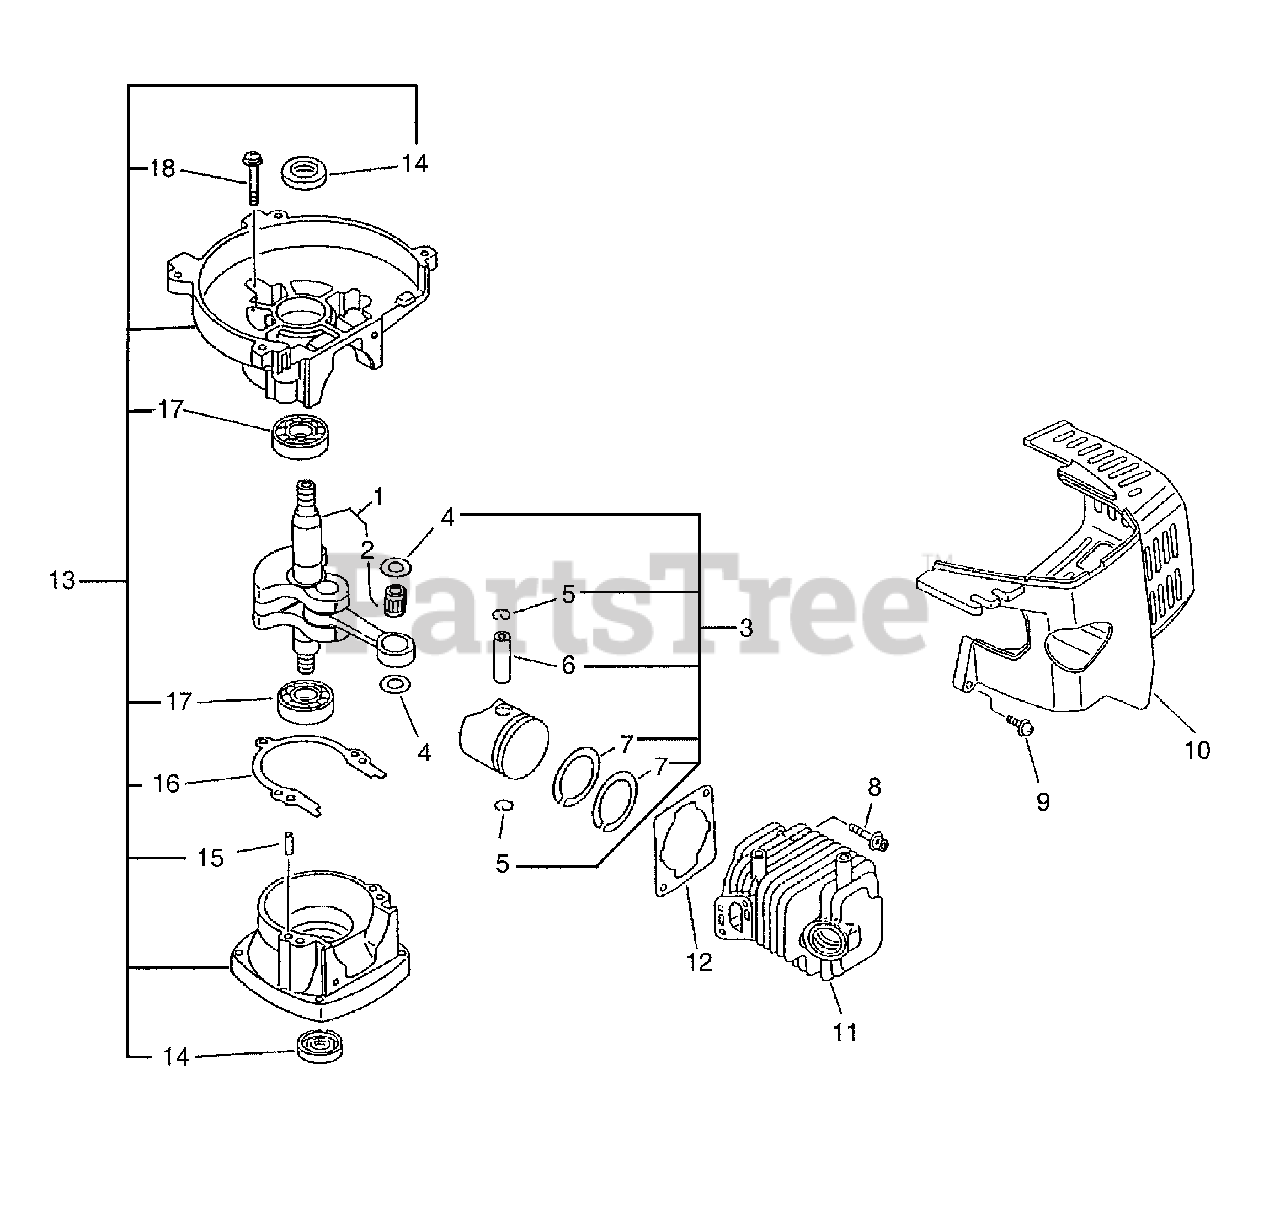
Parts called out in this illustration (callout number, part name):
1	CRANKSHAFT ASSY
2	BEARING, NEEDLE
3	PISTON KIT
4	WASHER, THRUST
5	RING, SNAP
6	PIN, PISTON 8
7	RING, PISTON
8	BOLT 5×22
9	SCREW 4×22
10	COVER, CYLINDER
11	CYLINDER
12	GASKET, CYLINDER
13	CRANKCASE KIT
14	SEAL, OIL 12
15	PIN, LOCATING 4
16	GASKET, CRANKCASE
17	BEARING, BALL - 6201 C3
18	BOLT 5×28
